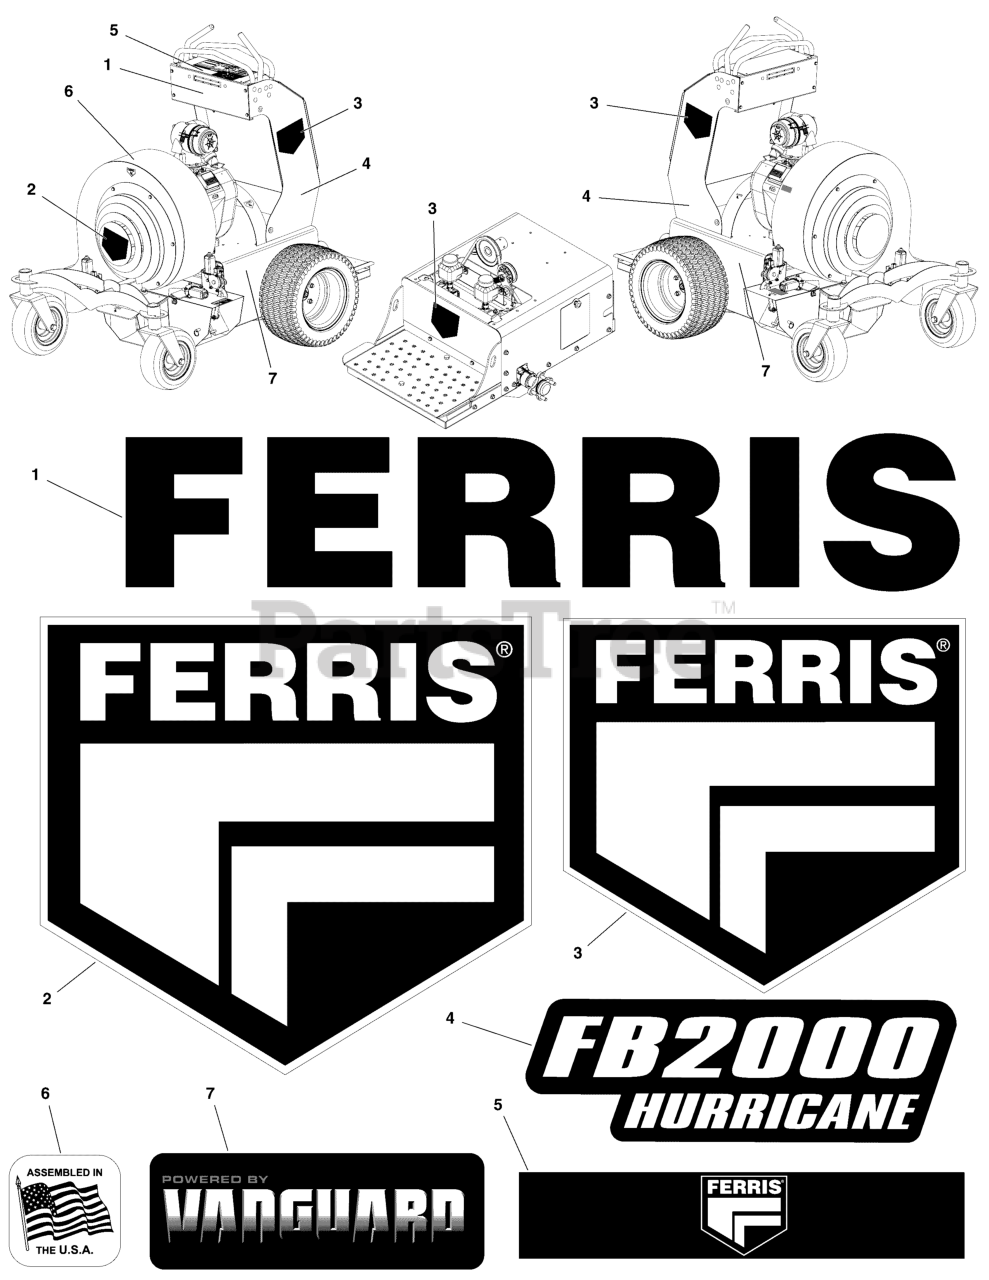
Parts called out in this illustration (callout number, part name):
1	DECAL, Brand
2	DECAL, MODEL
3	DECAL, Brand
4	DECAL, Model
5	DECAL, Controls
7	DECAL, BRAND
